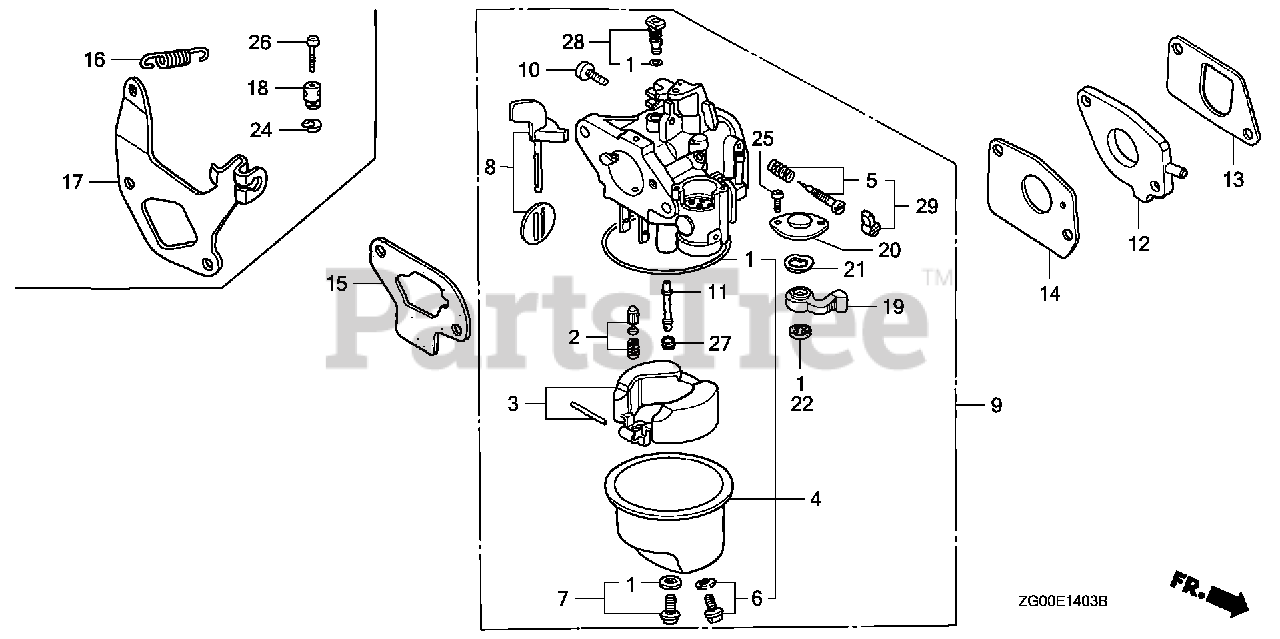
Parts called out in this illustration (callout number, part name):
1	GASKET SET
2	VALVE SET, FLOAT
4	CHAMBER SET, FLOAT (CARBURETOR NO.)
5	SCREW SET, PILOT (CARBURETOR NO.)
6	SCREW SET, DRAIN
7	SCREW SET
9	CARBURETOR ASSY. (BF12A B)
9	CARBURETOR ASSY. (BF12B C)
10	SCREW, THROTTLE STOP
11	NOZZLE, MAIN (CARBURETOR NO.)
12	INSULATOR, CARBURETOR
13	GASKET, INSULATOR
14	GASKET, CARBURETOR
15	GASKET, AIR CLEANER
19	LEVER, VALVE (CARBURETOR NO.)
20	PLATE, LEVER SETTING (CARBURETOR NO.)
21	SPRING, VALVE LEVER
22	GASKET, VALVE (CARBURETOR NO.)
25	SCREW, PAN (3X6)
27	JET, MAIN (#50) Use from Engine SN BF12A B.
27	JET, MAIN (#52) Use from Engine SN BF12A B.
27	JET, MAIN (#55) (CARBURETOR NO.)
27	JET, MAIN (#52) Use up to Engine SN BF12B C.
27	JET, MAIN (#55) Use up to Engine SN BF12B C.
27	JET, MAIN (#58) (CARBURETOR NO.)
28	JET SET, PILOT (#35) (CARBURETOR NO.)
28	JET SET, PILOT (#38) (CARBURETOR NO.)
28	JET SET, PILOT (#40) (CARBURETOR NO.)
29	SCREW SET (CARBURETOR NO.)
